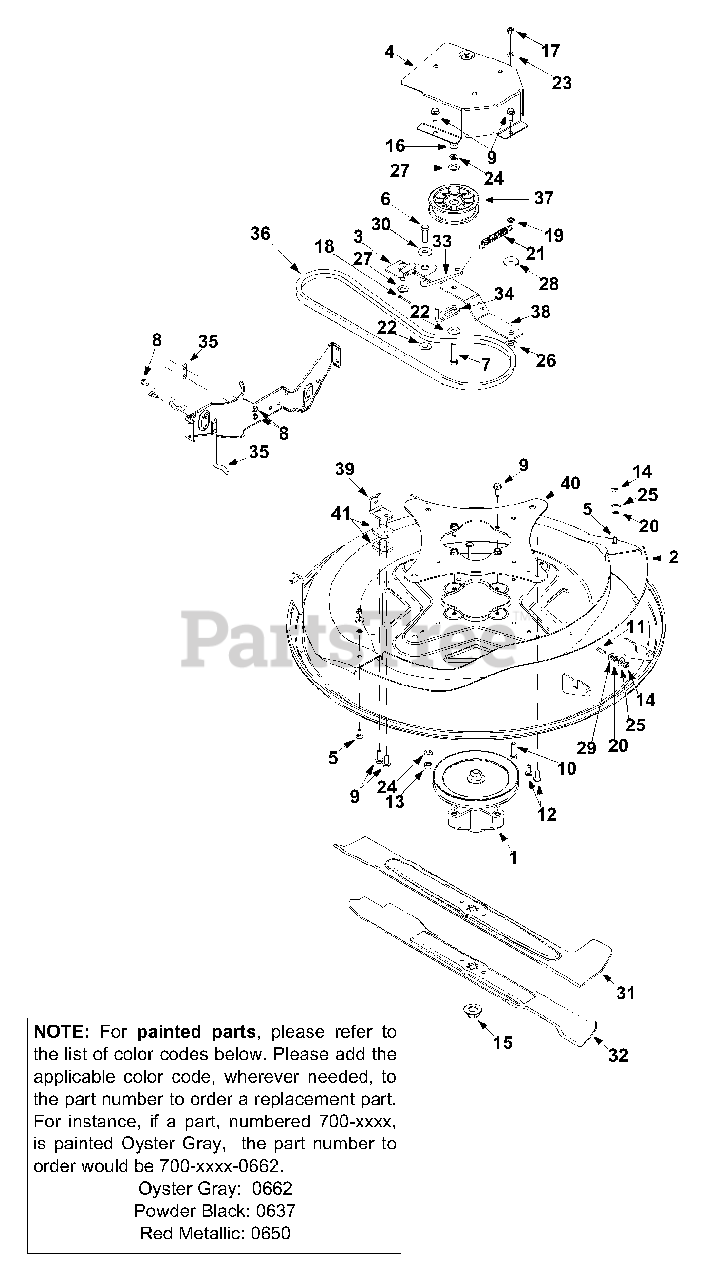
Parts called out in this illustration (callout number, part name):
1	Spindle Assembly
5	Carriage Screw 1/4-20 x .62"
6	Hex Bolt 3/8-24 x 1.25"
7	Hex Screw 3/8-16 x 1.75"
8	Self-Tapp. Screw 1/4-20 x .5"
9	Self-Tapp. Screw 5/16-18 x .75"
10	Hex Cap Scr. 5/16-24 x 1.25"
11	Carriage Screw
12	Torx Screw 5/16-18 x .75"
13	Hex Nut 3/8-24
14	Hex Nut 1/4-20
15	Flange Nut 5/8-18
16	Hex Nut 3/8-16
17	Hex Nut 5/16-24
21	Extension Spring
22	Flat Washer 3/8 x 1.00 x .030"
23	Lock Washer 5/16
24	Lock Washer 3/8
26	Bushing
27	Flat Washer .406 x .875 x .059"
28	Flat Washer .330 x 1.25 x .120"
30	Spacer
31	Blade: 27.5" Bagging
37	Flat Idler Pulley
